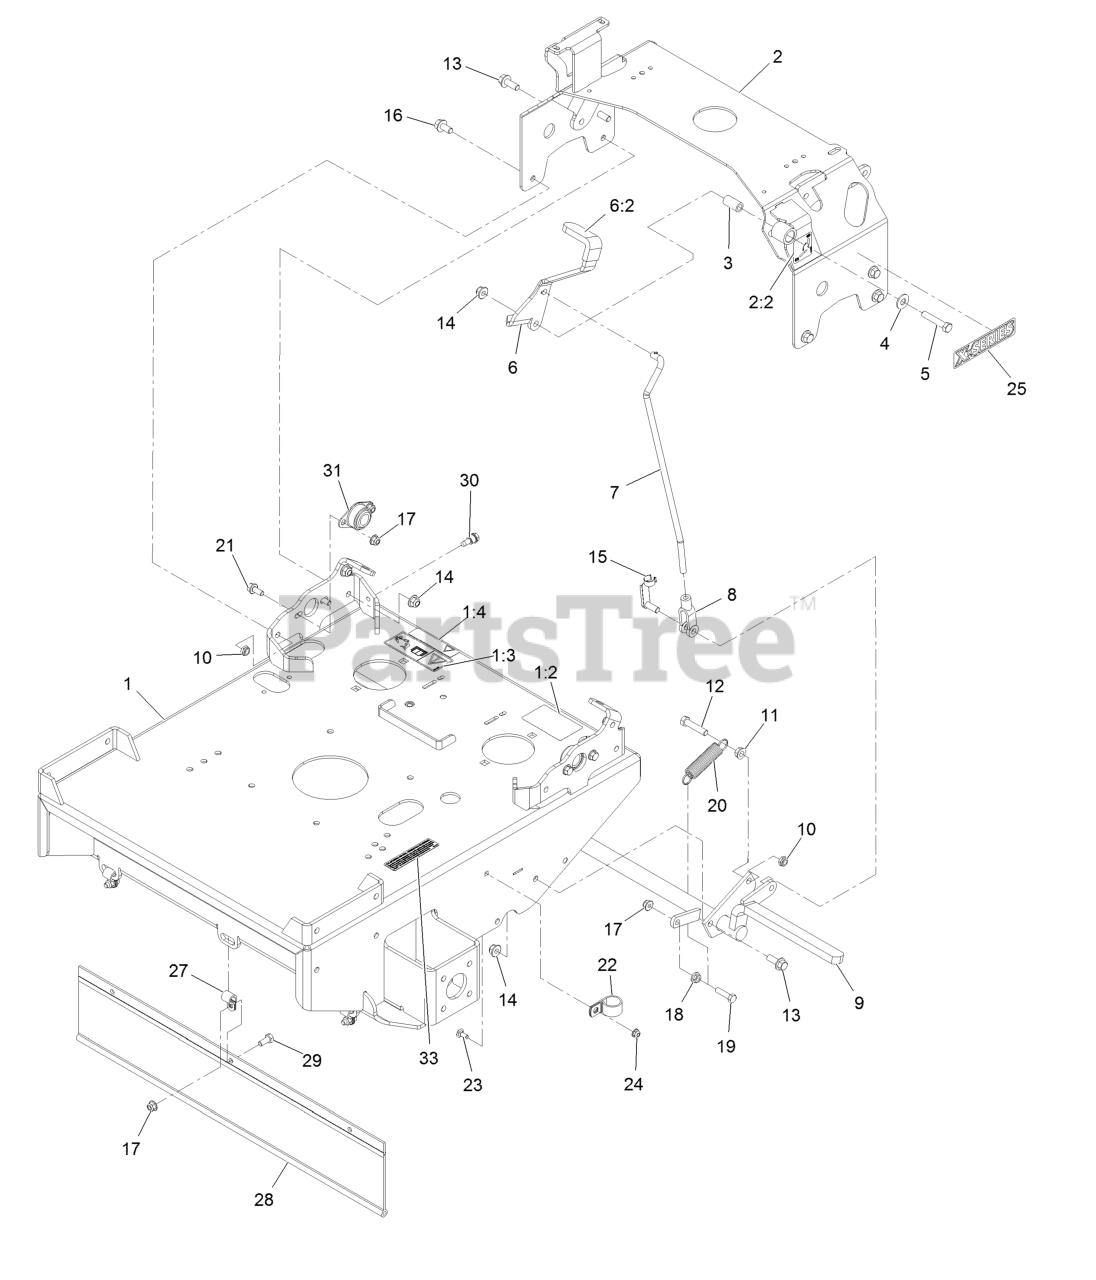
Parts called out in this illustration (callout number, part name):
1	ASM, ENGINE DECK W/ DECAL
1:2	DECAL-WARNING
1:3	DECAL-WARNING, SULKY
1:4	DECAL-DRIVE RELEASE
2	ASM, TANK SUPPORT W/ DECA
2:2	DECAL-PARK BRAKE, CE
3	BUSHING-PIVOT
4	WASHER-FLAT
5	SCREW-HH
6	ASM, BRAKE LEVER W/ GRIP
6:2	GRIP-LEVER
7	LINKAGE-BRAKE
8	YOKE-LINKAGE, BRAKE
9	WLD,BRAKE TTX
11	NUT-HHF, WHIZ
12	SCREW-HH
13	SCREW-HHF 3/8-16 X 1
14	NUT-HF, NI
15	PIN-SPRING, CLEVIS
16	SCREW-HHF
17	NUT-HF, NI
19	SCREW-HH
20	SPRING-IDLER
21	SCREW-HHF
22	CLIP-LOOM
23	SCREW-CARR
25	DECAL-X-SERIES
27	CLIP-LOOM
28	SHIELD,DRAG
29	SCREW-HH
30	BOLT-SHOULDER
31	BEARING-FLANGE, SIDE
33	DECAL-ARRESTER, SPARK
